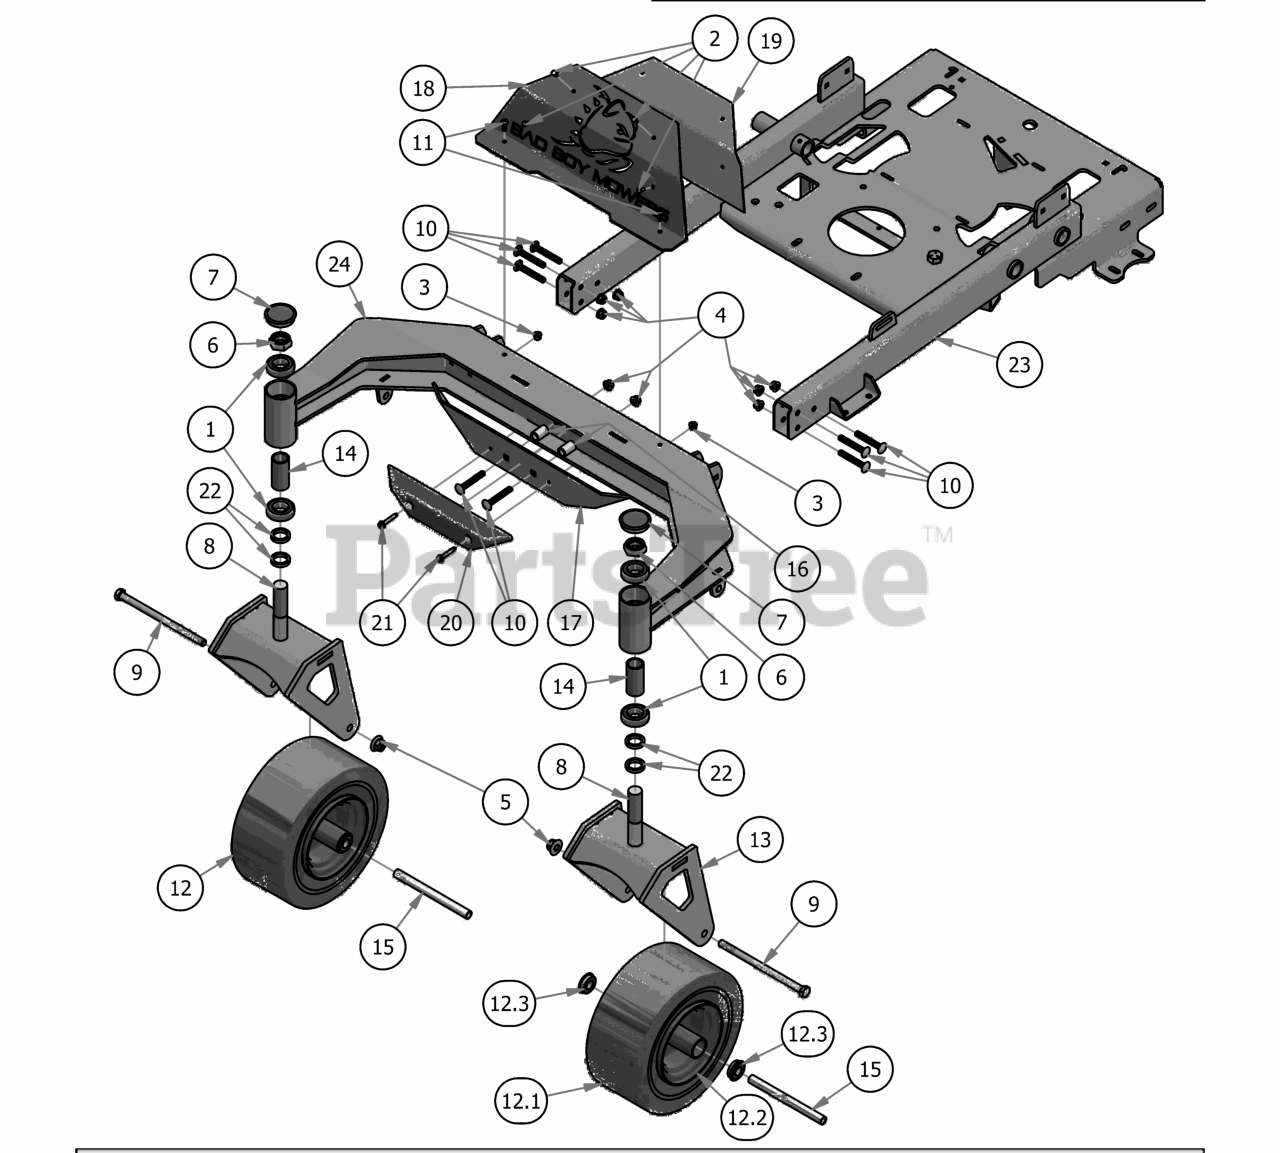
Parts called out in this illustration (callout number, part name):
1	Caster Bearing 2016 - 1641 Bearing
2	3/16 Rivet for .126-.25 THK
3	1/4-20 Nylon Insert flange Nut
4	3/8" Nylock Flange Nut
5	1/2-13 Nylon Flange Nut
6	1" Fine Thread 1/2 Nylock Nut
7	2017 Bearing Cover
8	1-14 x 5 Hex Bolt Grade 8 Zinc Yellow
9	1/2" x 8 1/2 GR 5 Hex Bolt
10	3/8" x 2 1/2" Carriage Bolt
11	1/4"-20 Thread, 3/4" Long
12	Tire and Wheel Assembly
12.1	13 x 6.50 - 6 Tire
12.2	Front Tire Rim
12.3	BEARING WITH RETAINER
13	2019 Stand-on Front Fork Weldment
14	2016 Front Bearing Spacer
15	Front Wheel Spanner
17	2019 Stand On Front Bumper Plate
18	2019 Stand On Exhaust Shield
19	2019 Stand On Exhaust Backer Plate
20	Bumper EZT
21	1/4" x 1 1/2" Self Tapping Screw
22	Spacer, 1x1.375x.25
23	2019 Stand On Frame Weldment
24	2019 Stand-On 48 Front End Weldment
